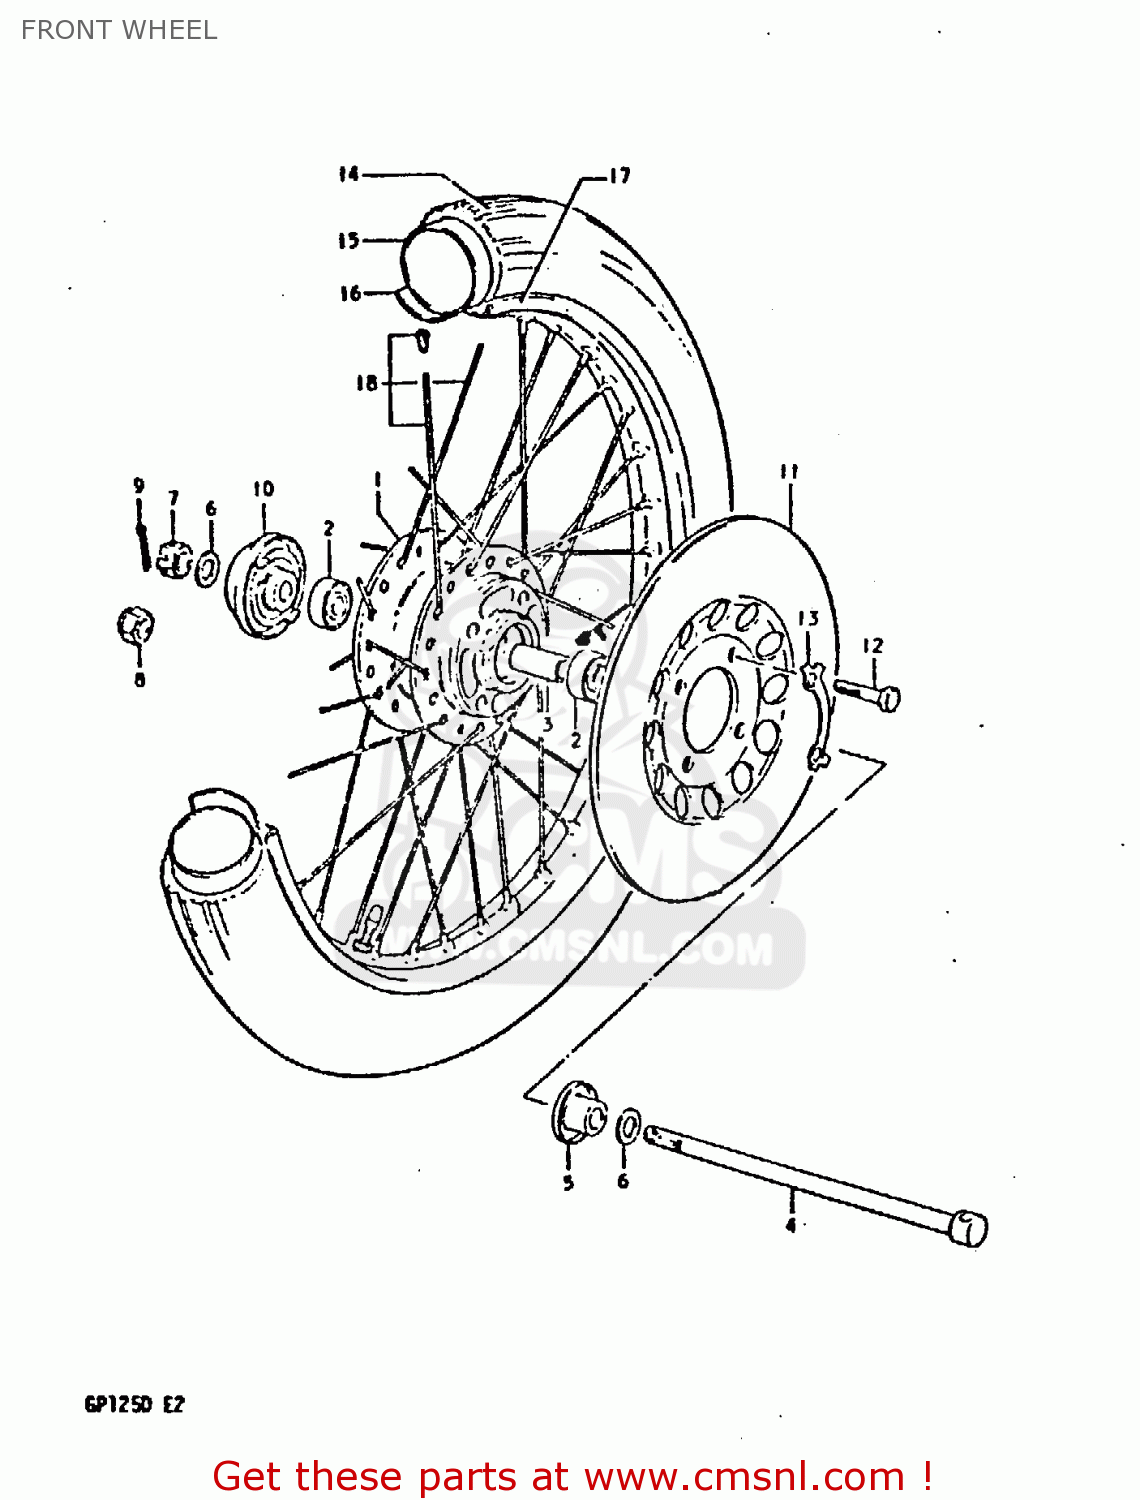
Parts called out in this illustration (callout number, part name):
1	HUB,FR
2	BEARING
3	SPACER (10.2X16X51)
4	AXLE,FRONT
5	SPACER,FR AXLE,L
6	WASHER
7	NUT
9	COTTER PIN
10	BOX ASSY,SPEEDOMETER GEAR
11	DISC,FR BRAKE
12	BOLT(8X30)
13	WASHER
14	TIRE,FRONT
15	TUBE,INNER
16	PROTECTOR,INNER TUBE
17	RIM,WHEEL
18	SPOKE SET,FRONT
